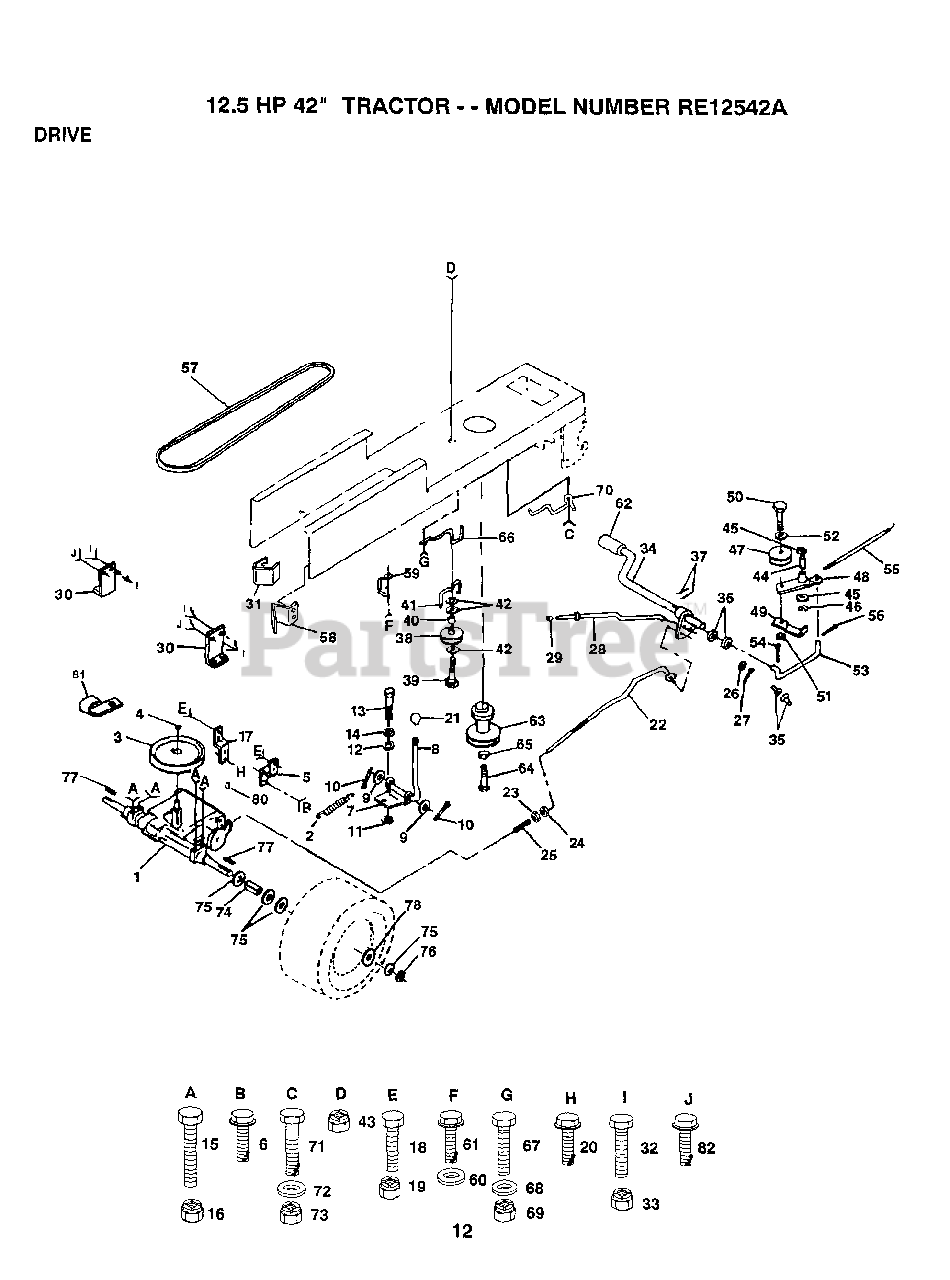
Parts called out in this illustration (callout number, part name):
3	PULLEY TRANS
5	STRAP TORQUE
6	SCREW
8	SHIFT ROD
9	WASHER
10	PIN COTTER 1/8
11	WASH-SHFT PLT LT
12	WASHER LT
14	LOCKWASHER
15	BOLT
17	STRAP TORQUE
20	SCREW
21	CONTROL KNOB LT
22	BRAKE ROD
23	NUT
24	NUT
25	SPRING ROD LT
26	WASHER
27	COTTER PIN
28	PARKING BRAKE ROD
30	TRANSAXLE MTG BKT
31	"KEEPER,BELT LH T"
32	BOLT
35	NYLON BEARING
36	WASHER LT
38	PULLEY.IDLER.FLAT
39	BOLT
40	SPACER T
41	BELT KEEPER LT
42	WASHER
44	"LY, BEARING"
45	WASHER LT
46	KLIP RING
48	ARM IDLER
49	RETAIN BELT
52	WASHER
53	"LINK, CLUTCH T"
54	COTTER PIN
55	"SPRING, RETURN LT"
56	COTTER PIN
58	"KEEPER,BELT RH T"
60	WASHER
61	SCREW
62	PEDAL COVER T
64	BOLT
65	LOCKWASHER
66	KEEPER.BELT.ENG.L
67	BOLT
68	WASHER
70	KEEPER BELT ENG
71	BOLT
72	WASHER
74	SPACER LT
75	WASHER
76	E-RING LT
77	SQUARE KEY
78	WASHER
81	CLIP T
82	SCREW
